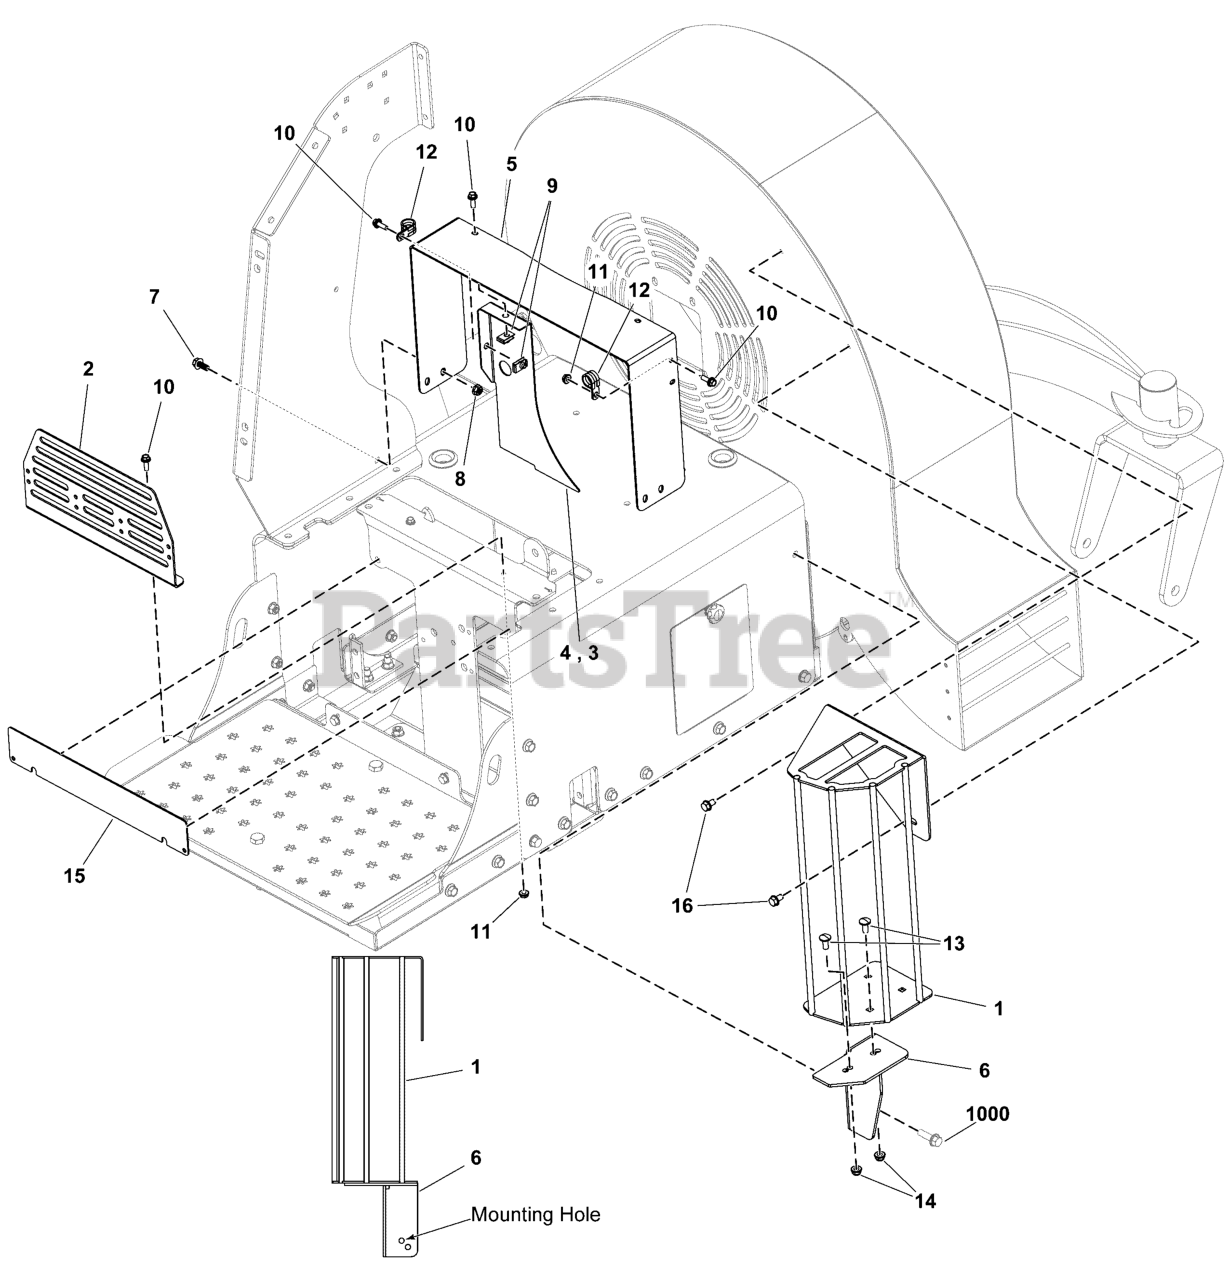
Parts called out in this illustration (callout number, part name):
1	WELD,MUFFLER GUARD,HURRICANE,Z3000 - BLK
2	MOUNT, OIL RESERVOIR, CE - BLK
4	PLATE, LH REAR BELT GUARD, CE - ORG
5	PLATE, REAR BELT GUARD, CE - ORG
6	WELD, LOWER SUPPORT, MUF GUARD - BLK
7	SCREW, 5/16-18x0.750, GR5, WHIZ-LOCK, ZC
8	NUT, 5/16-18 HEX SERRATED FLANGE (SMALL)
9	BODY CLIP, 1/4-20 X 1/2" DEEP
10	BOLT, 1/4-20 X 3/4, FLANGE, CZ
11	NUT, 1/4-20 HEX SERR. FLANGE
12	CLAMP, VINYL INSULATED, .75
13	RHSSNB,5/16-18 X 3/4 GR5 ZINC/CLEAR
14	NUT, 5/16-18 HEX NYLOCK FLANGE NUT
15	PLATE, TRANSMISSION GUARD - BLK
16	SCREW,5/16-18X0.625,WSHR,THD-ROLL,ZC/CL
1000	Refer to: Main Frame Group
